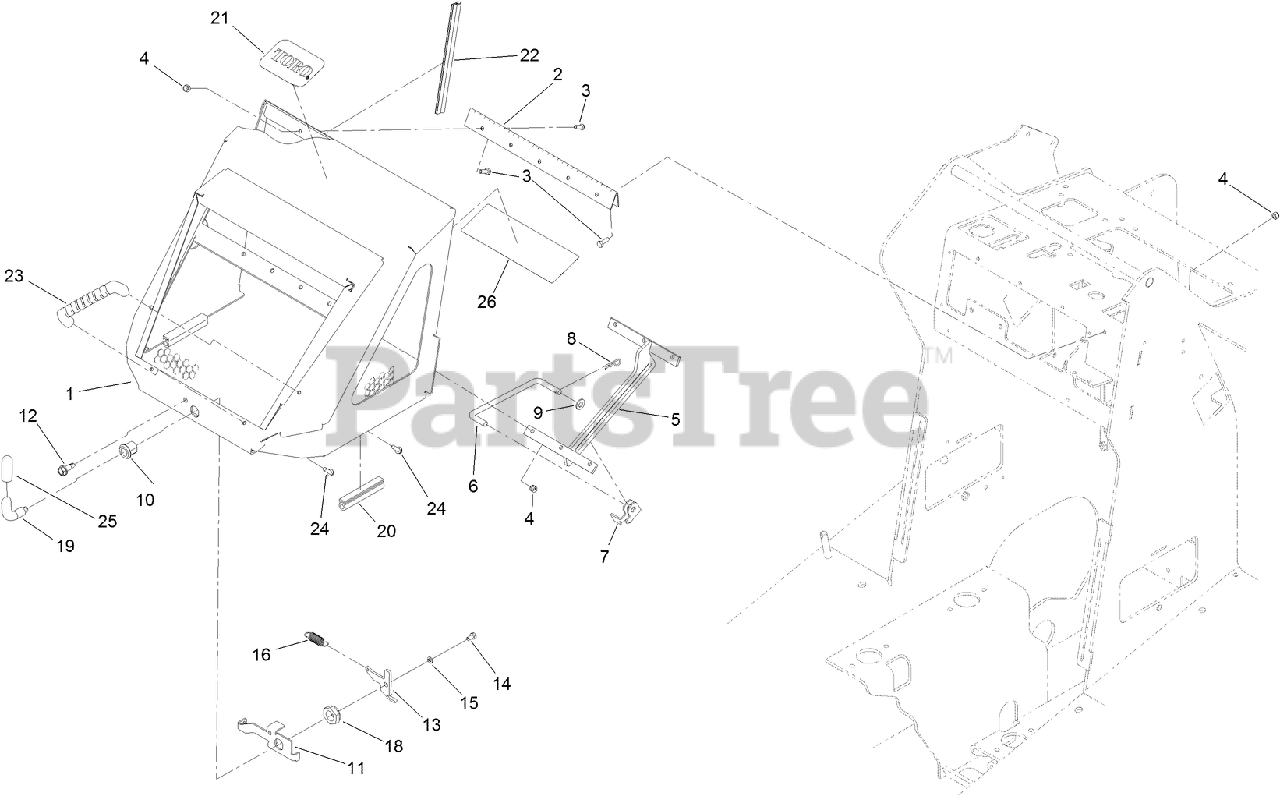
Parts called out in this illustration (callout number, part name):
1	ENGINE HOOD ASM
2	HINGE-HOOD
3	SCREW-HH
4	NUT-LOCK, NI
5	BRACKET-PROP, HOOD
6	ROD-SUPPORT, HOOD
7	BRACKET-LATCH, LOCKING
8	PIN-COTTER
9	WASHER-FLAT
10	HOUSING-LATCH
11	BRACKET-LATCH
12	SCREW-TAPPING
13	CAM-HOOKED
14	SCREW-HH
15	SCREW-HH
16	SPRING
19	HANDLE-LATCH
20	PAD-HOOD
22	TRIM-SEAL, BULB
23	HANDLE-DOOR
24	SCREW-HWH
25	GRIP-LEVER, HOOD
26	DECAL-SERVICE
26	DECAL-SERVICE, FRENCH
26	DECAL-SERVICE, GERMAN
26	DECAL-SERVICE, SPANISH
26	DECAL-SERVICE, ITALIAN
26	DECAL-SERVICE, DUTCH
26	DECAL-SERVICE, POLISH
26	DECAL-SERVICE, RUSSIAN
26	DECAL-SERVICE, SLOVAK
